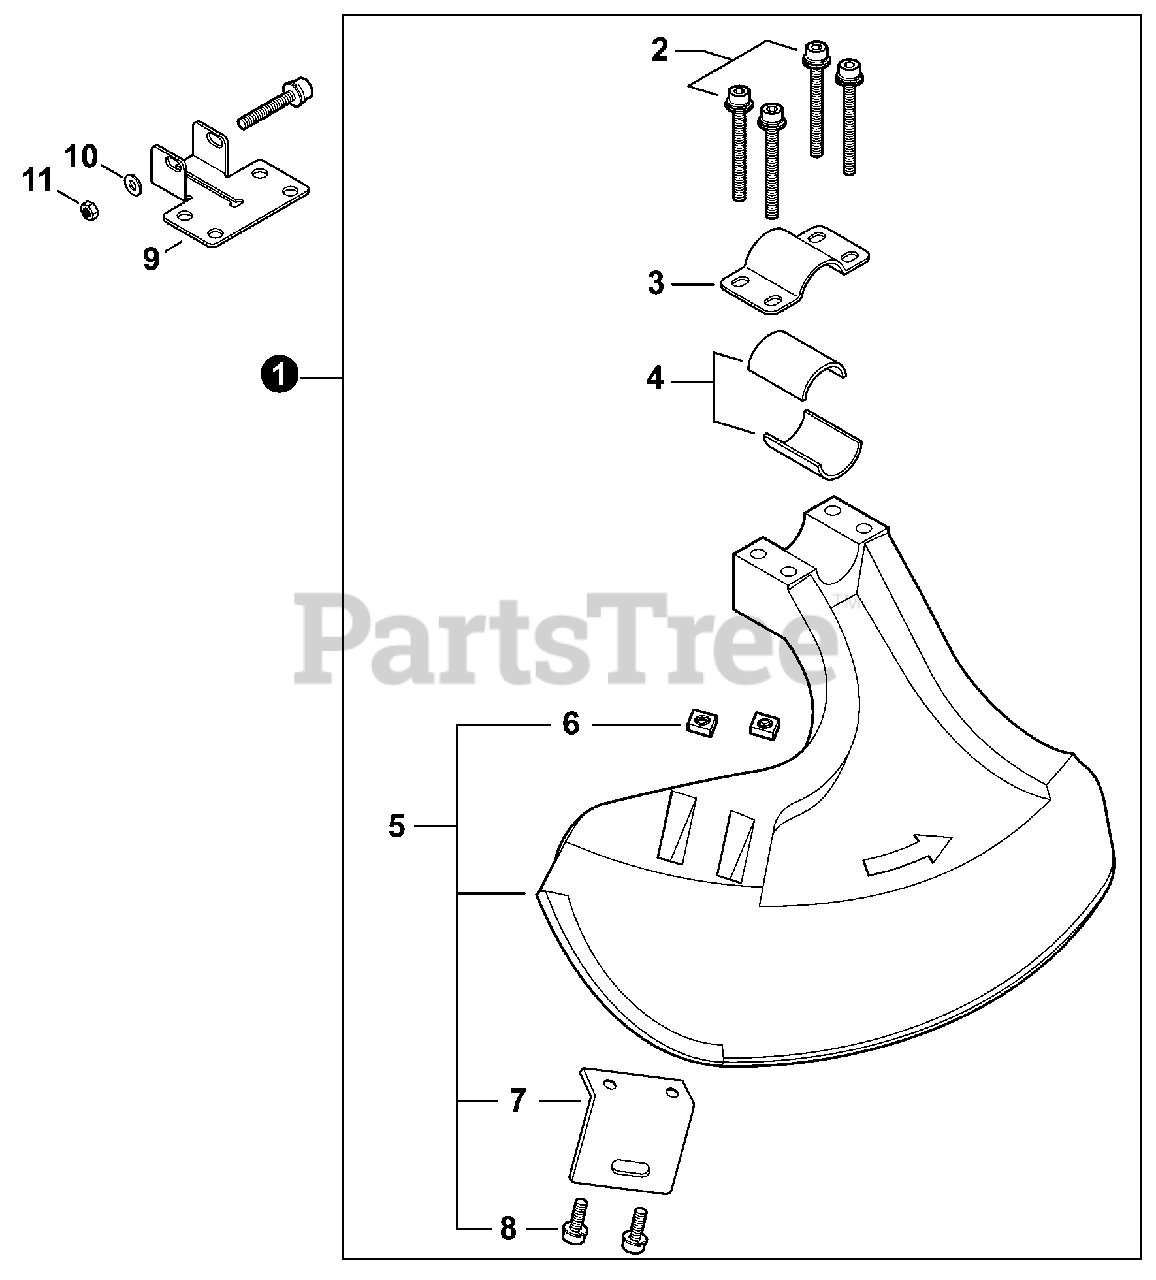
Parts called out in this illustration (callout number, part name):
1	DEBRIS SHIELD KIT
2	BOLT M5×45
3	CLAMP, UPPER
4	SPACER 26
5	DEBRIS SHIELD ASSY
8	BOLT 5×16
9	PLATE, SHIELD MOUNTING
10	WASHER 6.5×13×1
11	NUT, HEX M6
